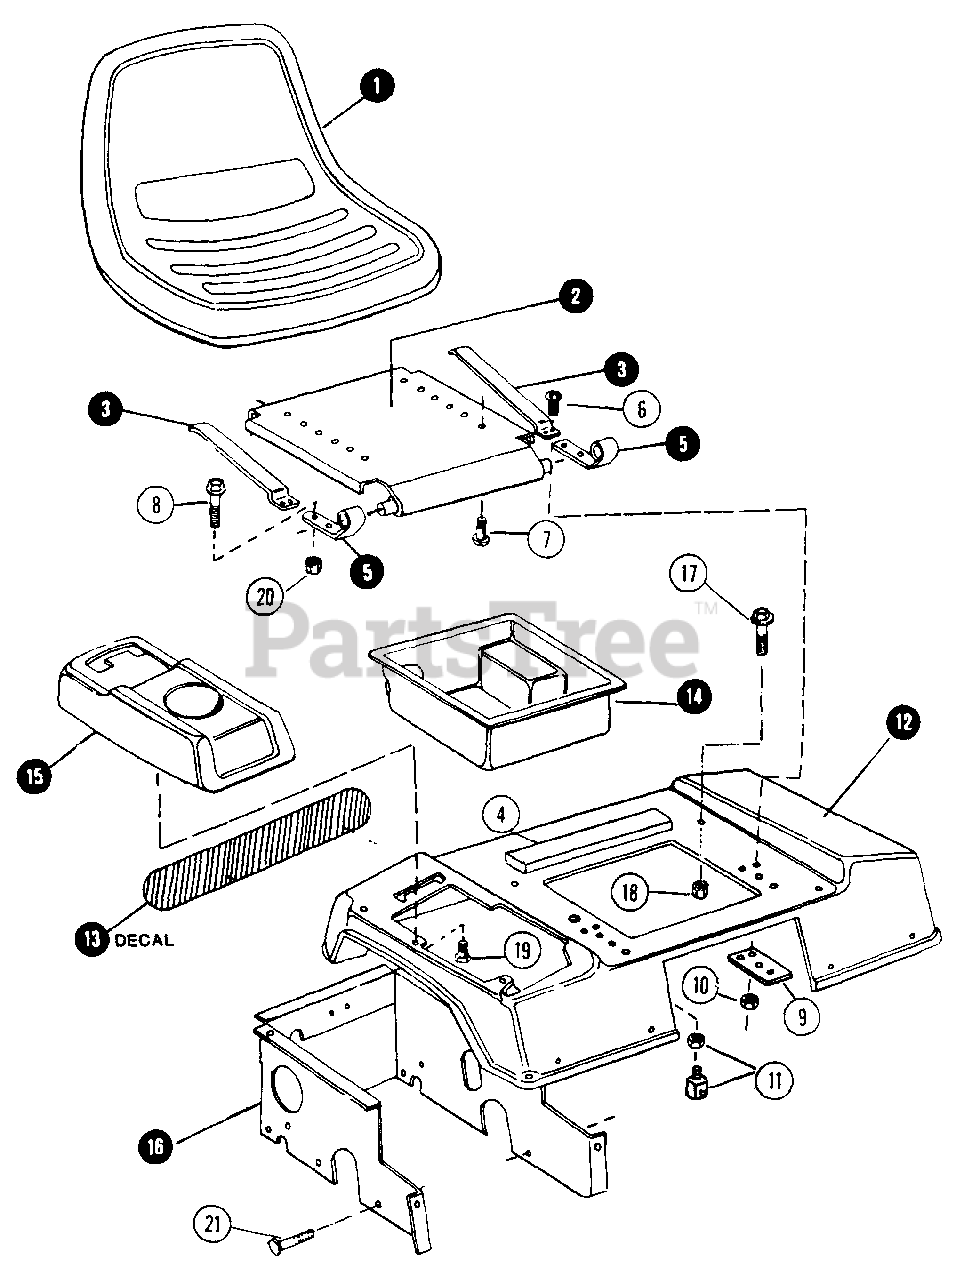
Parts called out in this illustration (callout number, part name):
1	SEAT, OPERATOR'S
2	PLATE, SEAT BASE
3	SPRING, SEAT
4	PAD, 3/4 x 10-38"
5	HINGE, SEAT
6	SCREW, #10-24 x 5/8 SLOT ROUND HEAD
7	BOLT, 5/16C x 3/4 HEX FLANGE LOCK
8	BOLT, 1/4C x 5/8 HEX FLANGE
9	PLATE, SEAT RETAINER
10	NUT, #10-24 HEX LOCK
11	SWITCH, SEAT INTERLOCK
12	FENDER, REAR
13	DECAL, SNAPPER (REAR FENDER)
14	COMPARTMENT
15	COVER, FENDER
16	RISER, REAR FENDER
17	BOLT, 5/16C x 5/8 HEX FLANGE LOCK
18	NUT, 5/16C HEX FLANGE LOCK
19	SCREW, 1/4C x 5/8 SELF TAPPING
20	NUT, 1/4-20 HEX
21	BOLT, 3/8-16 x 7/8
